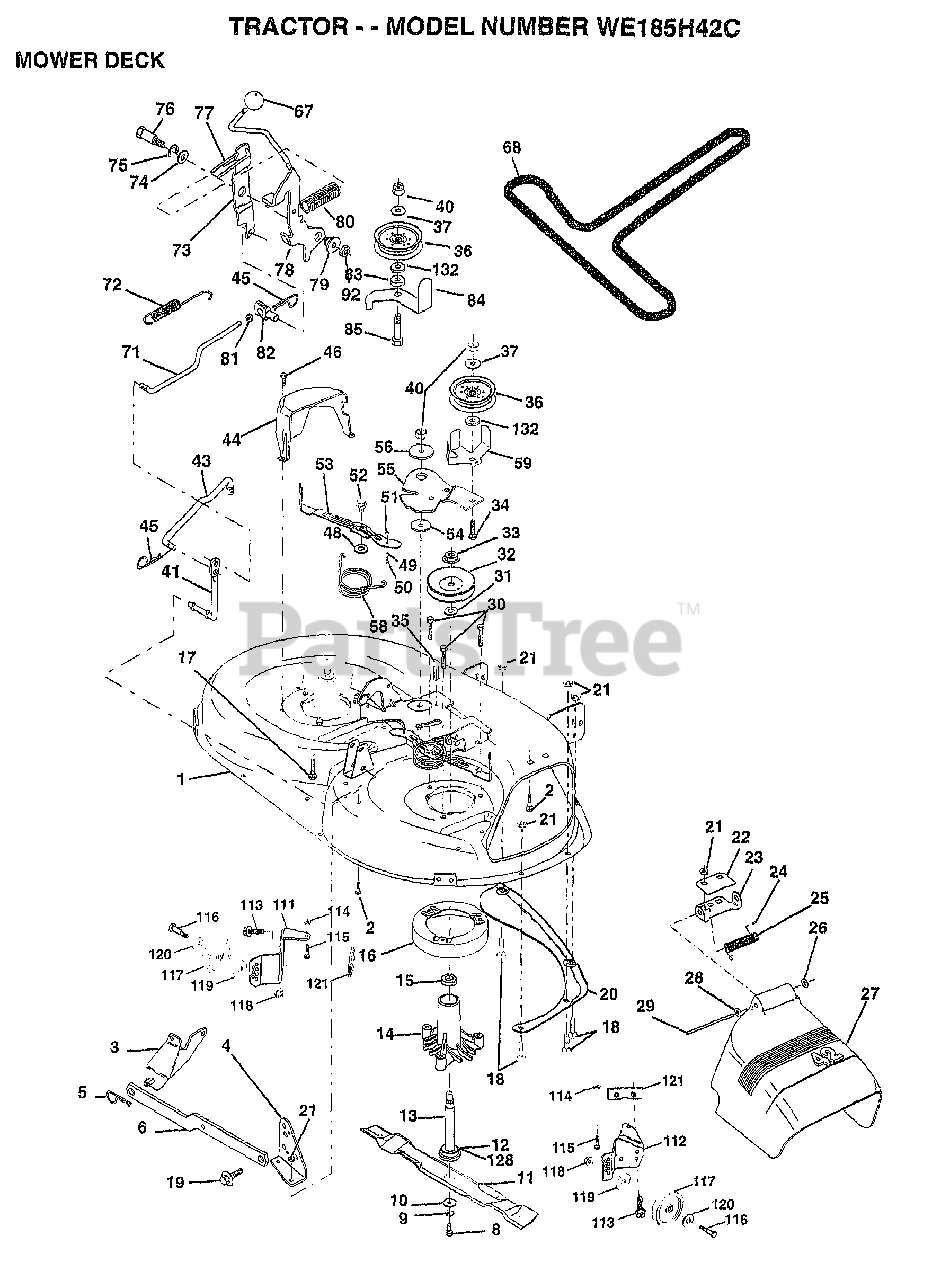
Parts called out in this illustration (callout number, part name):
1	DECK.WELD.42.
2	BOLT
3	BRKT ASM SWAY BAR
4	BRKT DECK SW BAR
8	BLADE BOLT
10	WASHER.HARD.BLADE
11	"BLADE.42"" HIPERF"
12	BEARING.BALL
14	HSG ASM MANDREL
15	BEARING
16	STRIPPER RND MWR
17	BOLT RDHD 3/8-16
18	BOLT
19	BOLT SHD 5/16-18
22	STIFFENER BRKT
23	DEFLECTOR BRKT
24	CAP-SLEEVE LT
25	SPRING TORSION
26	NUT PUSH M
27	DEFLECTOR.SHIELD
28	WASHER
29	HINGE ROD
30	"SCREW-THD ROLL,WA"
31	WASHER
32	PULLEY.MANDREL.42
34	BOLT
35	XMAS TREE FASTNER
36	FLAT IDLER PULLEY
37	WASHER
41	PIVOT ROD
43	ROD CLUTCH W/NIBS
44	GUARD MAND LH BLK
45	RETAINER M
46	SCREW.1/4-20X5/8
48	HARD SMALL WASHER
49	ROLLER ASM-CAM
50	SHOULDER BOLT
51	LOCKNUT
52	BOLT.SHLD.5/16-18
54	HARDENED WASHER
55	ARM-IDLER
56	SPACER RETAINER
58	SPRING TORSN BRAK
59	GUARD IDLER TUV
67	KNOB T(3/8 HOLE)
68	BELT-V.SEC.46.KEL
71	ROD CLUTCH 38/42
72	RETURN SPRING
73	CLUTCH ARM SECOND
74	WASHER
75	RING
76	SHOULDER BOLT
77	SPRING KEEPER
78	LEVER ASM-CLUTCH
79	BUSHING
80	SPRING.CLUTCH.MWR
81	NUT
82	TRUNION ADJ
84	BRACKET ASM IDLER
92	NUT
111	BRACKET.GWHL.LH.
112	BRACKET.GWHL.RH.
113	SCREW
116	BOLT M
117	WHEEL.GAGE.BLK.PL
118	LOCKNUT
119	WASHER
120	WASHER
121	BRACKET.EXTRD.GWL
128	WASHER.FELT.
132	WASHER GT
